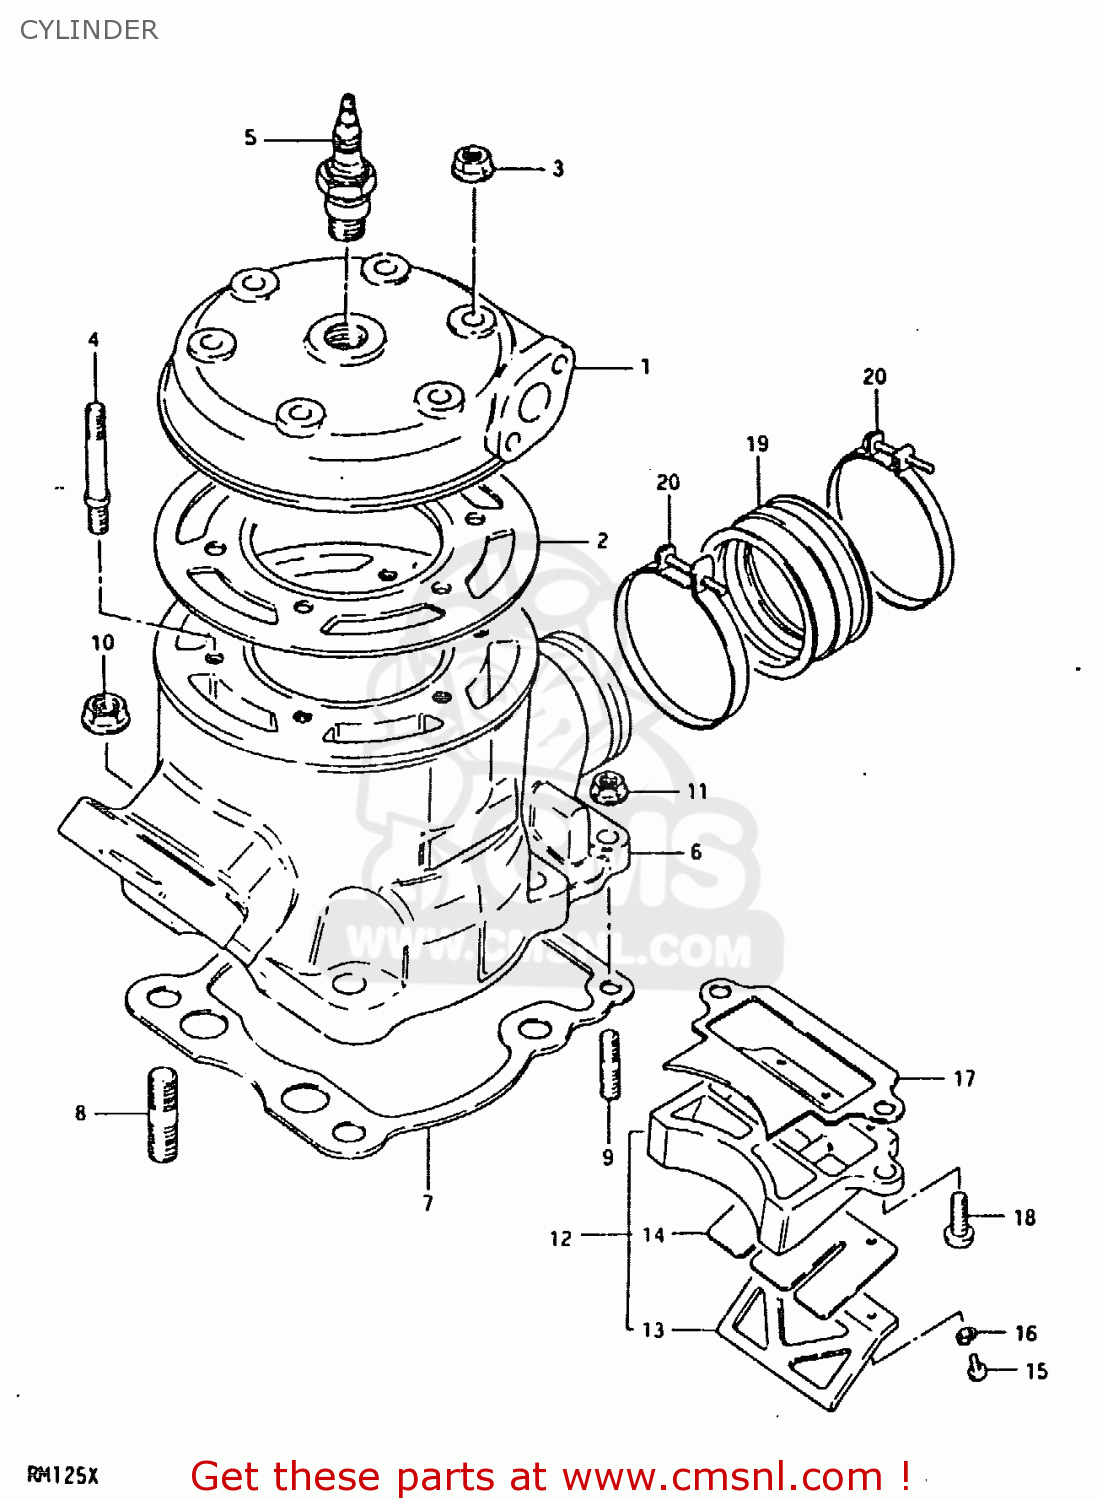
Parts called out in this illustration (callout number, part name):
1	HEAD,CYLINDER
2	GASKET,CYLINDER HEAD (MCA)
3	NUT
4	BOLT,STUD
5	SPARK PLUG
6	CYLINDER
7	GASKET,CYLINDER (MCA)
8	STUD 8X25
9	STUD 6X20
10	NUT
11	NUT
12	VALVE ASSEMBLY,REED
13	STOPPER,REED VALVE
14	VALVE,REED
15	SCREW
16	LOCK WASHER
17	GASKET,REED VALVE (MCA)
18	SCREW
19	PIPE,INTAKE
20	CLAMP
